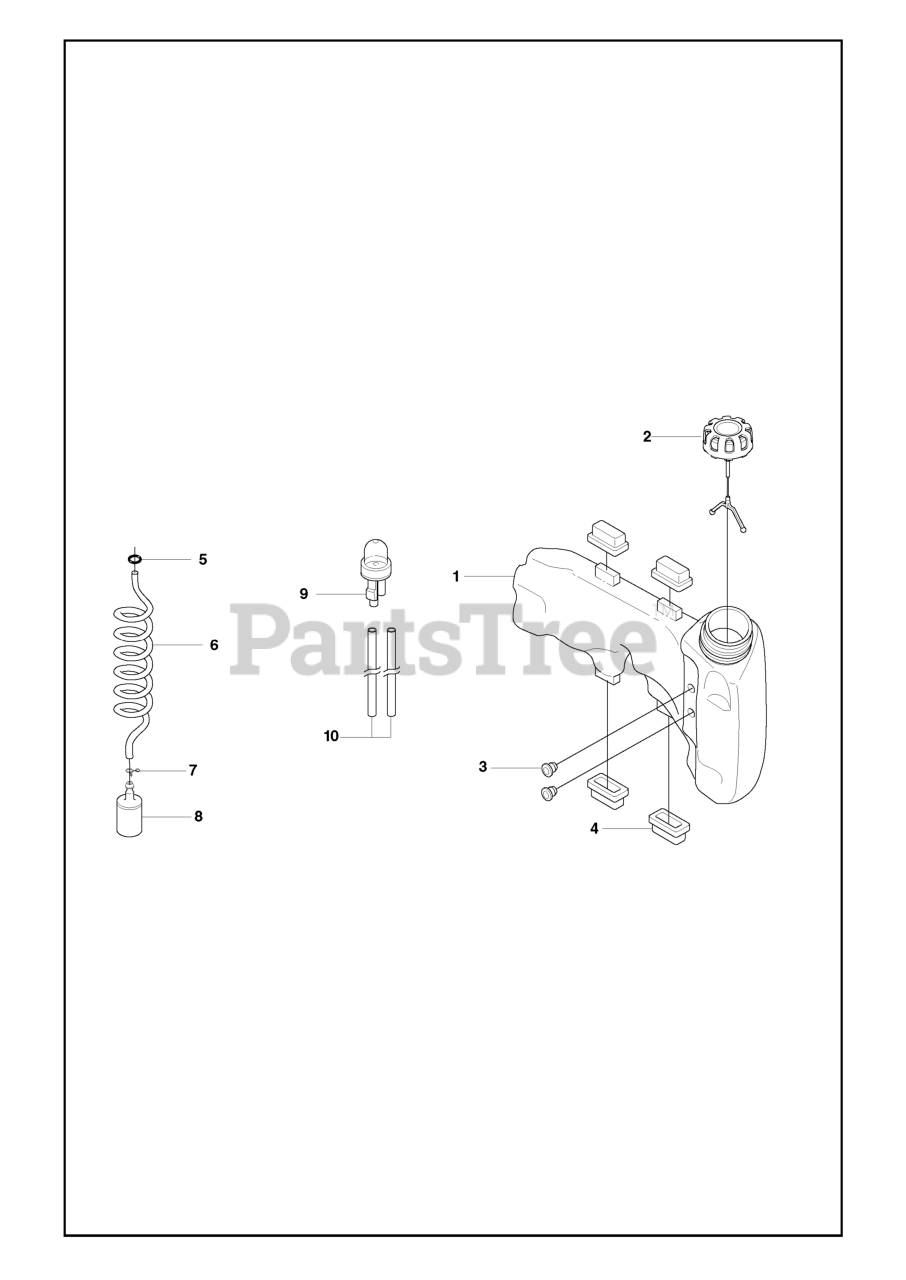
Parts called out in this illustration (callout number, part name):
2	TANK CAP
3	FUEL TANK BUSHING
6	FUEL HOSE
7	HOSE CLAMP
8	RP FUEL FILTER
9	AIR PURGE BUBBLE
10	HOSE
